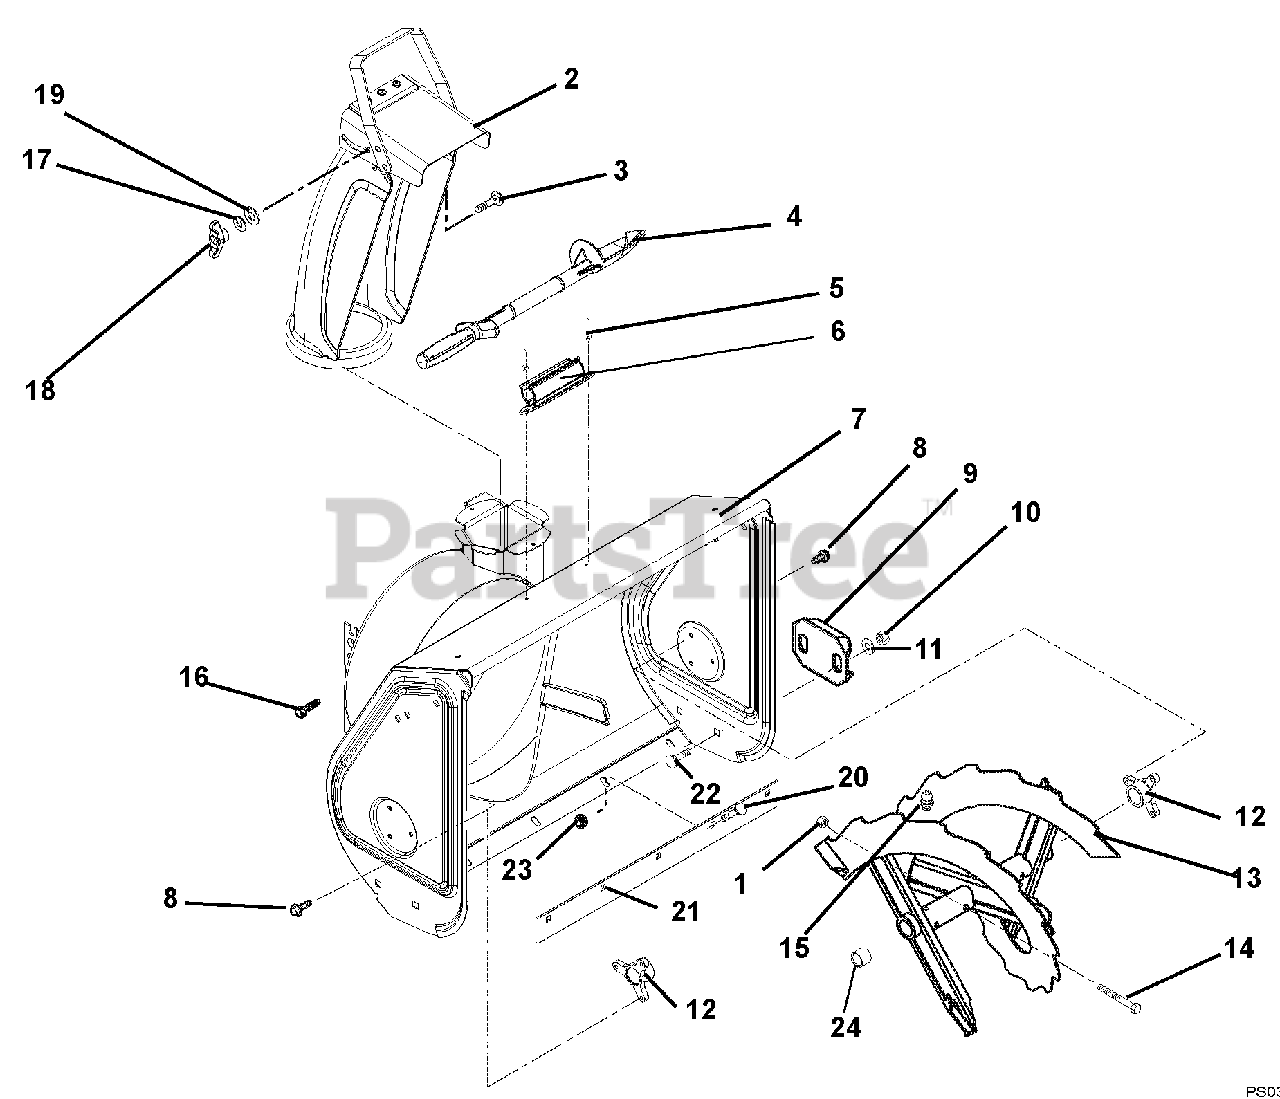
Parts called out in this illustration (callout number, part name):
1	@NUT-LK-CTR .25-20 YWZC
2	CHUTE, DISCHARGE W/CAP & DECAL
3	@BLT-RHDSSQNK .31-18X1.00 G5YZ
4	DEVICE, SNOW CLEAN OUT
5	RVT-POP .187 YZ
6	MOUNT, SNOW CLEAN OUT
7	BLOWER HOUSING, 24" HI ORANGE
8	SCR-TAP .25-20X.50 HWH TR YWZ
9	SKID SHOE, REVERSIBLE - BLACK
10	@NUT-LK-CTR .38-16 YWZC
11	@WSHR-FL-STL.38X.875X.083 YWZC
12	BUSHING, RAKE SHAFT .75"
13	AUGER, 20" RH, BLK SERR W/ZERK
14	SHEAR BOLT WITH NUT
15	ZERK,FITTING .25X.125 DRIVE IN
16	@SCR-TAP .31-18X.50 HWH TR YWZ
17	@WSHR-FL-STL.344X.688X.065YWZC
18	KNOB,WING .31-18 UNC NYL/TALC
19	WSHR-FL-NY .375X.75X.060
20	BLT,RDSHHDSQSHNK .31-18X.62 YZ
21	SCRAPER BLADE, 22" COMPACT HI
22	@BLT-RHDSSQNK .38-16X.75 G5YZ
23	@NUT-LK-TOP-FLG .31-18 YWZC
24	BSHG-SLV .75X1.12X1.062 NYL BK
